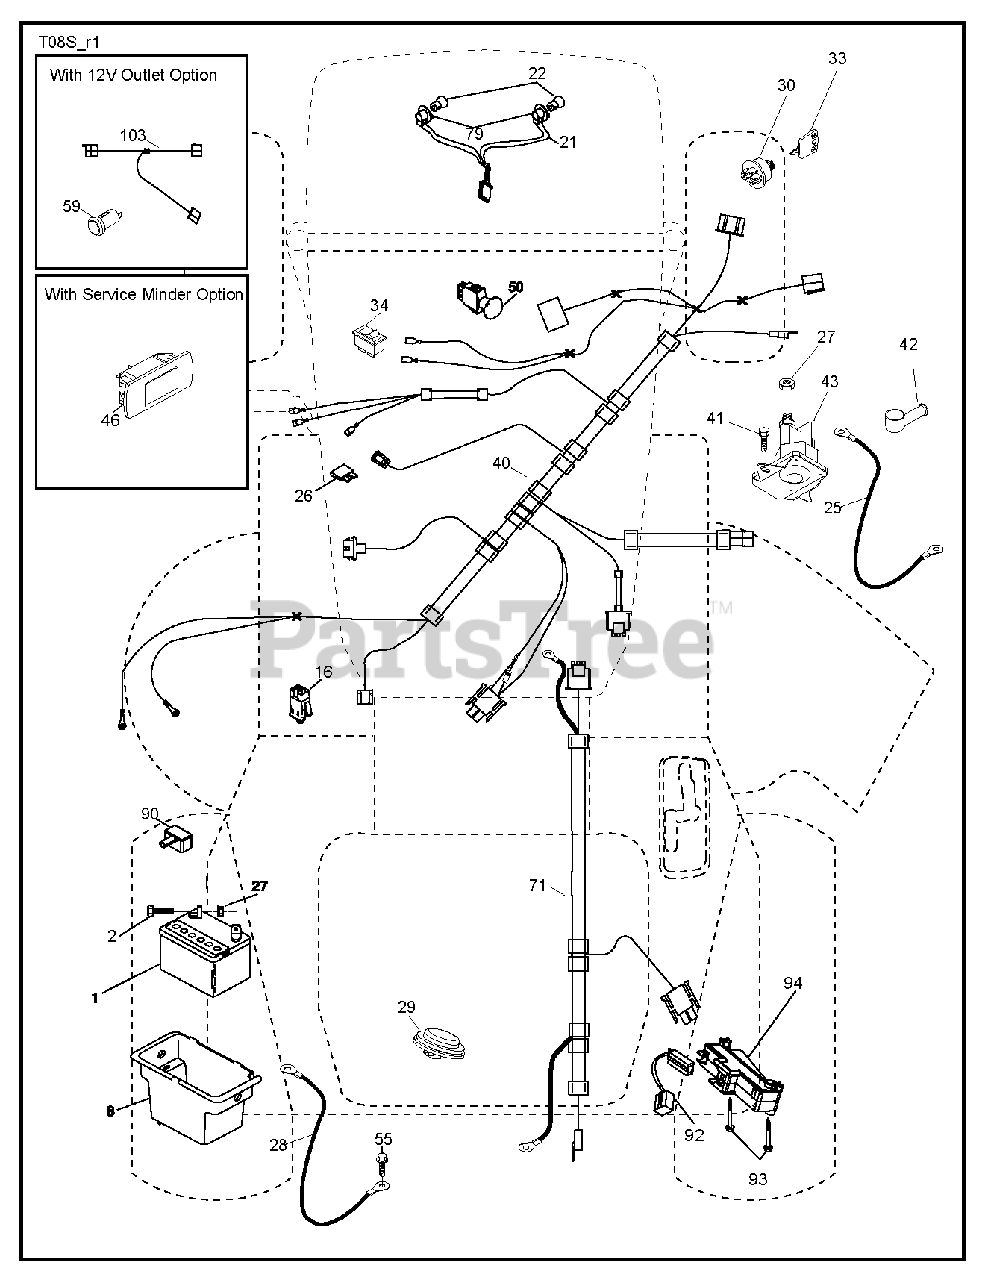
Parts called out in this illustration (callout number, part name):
1	REPL BY 532 12 38-99
8	BOX.BATTERY.MNT.REAR.L
16	SWITCH INTERLOOK PUSH-IN
21	HARNESS.LIGHT W/4152J BULBS
22	LIGHTBULB
25	CABLE.STARTER.6G.BL/RED.17.5
26	FUSE 20AMP
27	NUT
28	CABLE.BLACK.18"REAR.BA
29	SWITCH.SEAT.DELTA.OPC.
30	SWITCH.IGN.DELTA.W.LGH.ROS
33	KEY.CHAIN.BLISTER.PACK.GEN.INT
34	SWITCH LT
40	HARNESS.IGN.DASH.HUQ/P
41	SCREW
42	TERMINAL COVER
43	SOLENOID.W/BRASS.PLUNG
46	GUAGE.SRVCMNDR.HRMTR.
50	PTO SWITCH
55	SCREW 5/16"
71	HARNESS.IGN.CHASS.TEX.REAR.BAT
79	BULB HOLDER ASM.
90	COVER, TERMINAL BATTERY
92	HARNESS.PIGTAIL.CONSLE
93	SCREW.PLASTITE
94	MODULE.REVERSE.ROS
